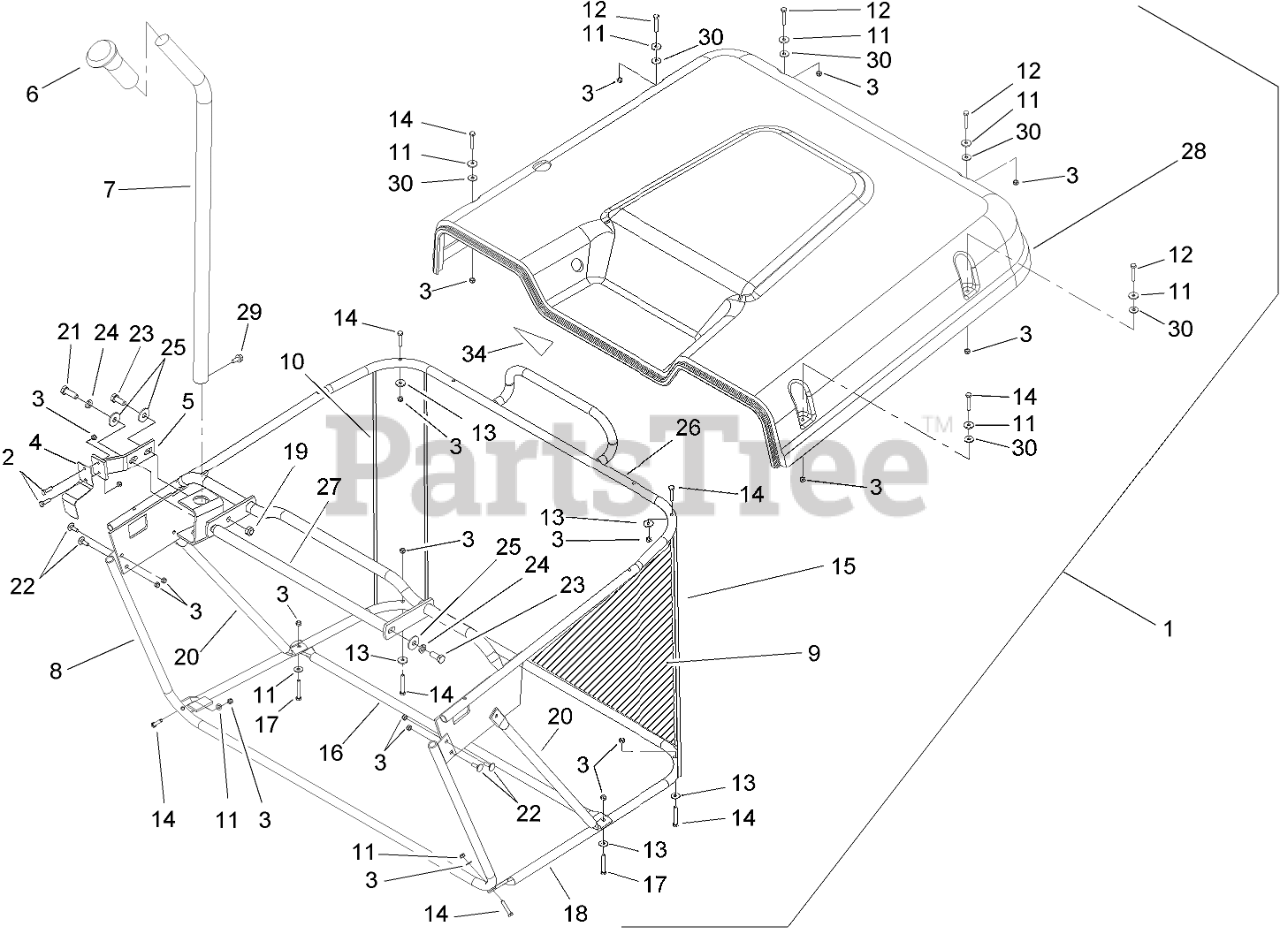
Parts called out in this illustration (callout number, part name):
2	SCREW-HH
3	NUT-LOCK
4	SPRING-COLL, INTERLOCK SWITCH
5	Bracket-Spring
6	GRIP-HANDLE
7	LEVER-DUMP
8	FRONT FRAME ASM
9	BAG-GRASS
10	SUPPORT-CORNER, RIGHT
11	WASHER-FLAT
13	WASHER
14	SCREW-HEX
15	SUPPORT-CORNER, LEFT
16	BRACE-CONNECTING
17	SCREW-HEX
18	BOTTOM FRAME ASM
19	NUT-LOCK, NI
21	SCREW-HH
22	BOLT-CARRIAGE
23	SCREW-HH
24	WASHER-LOCK, SPRING
25	WASHER-PLAIN
26	TOP FRAME ASM
27	HANDLE-LIFT
28	Cover-Collector
30	WASHER-RUBBER
34	DECAL-BAG TO FRAME
